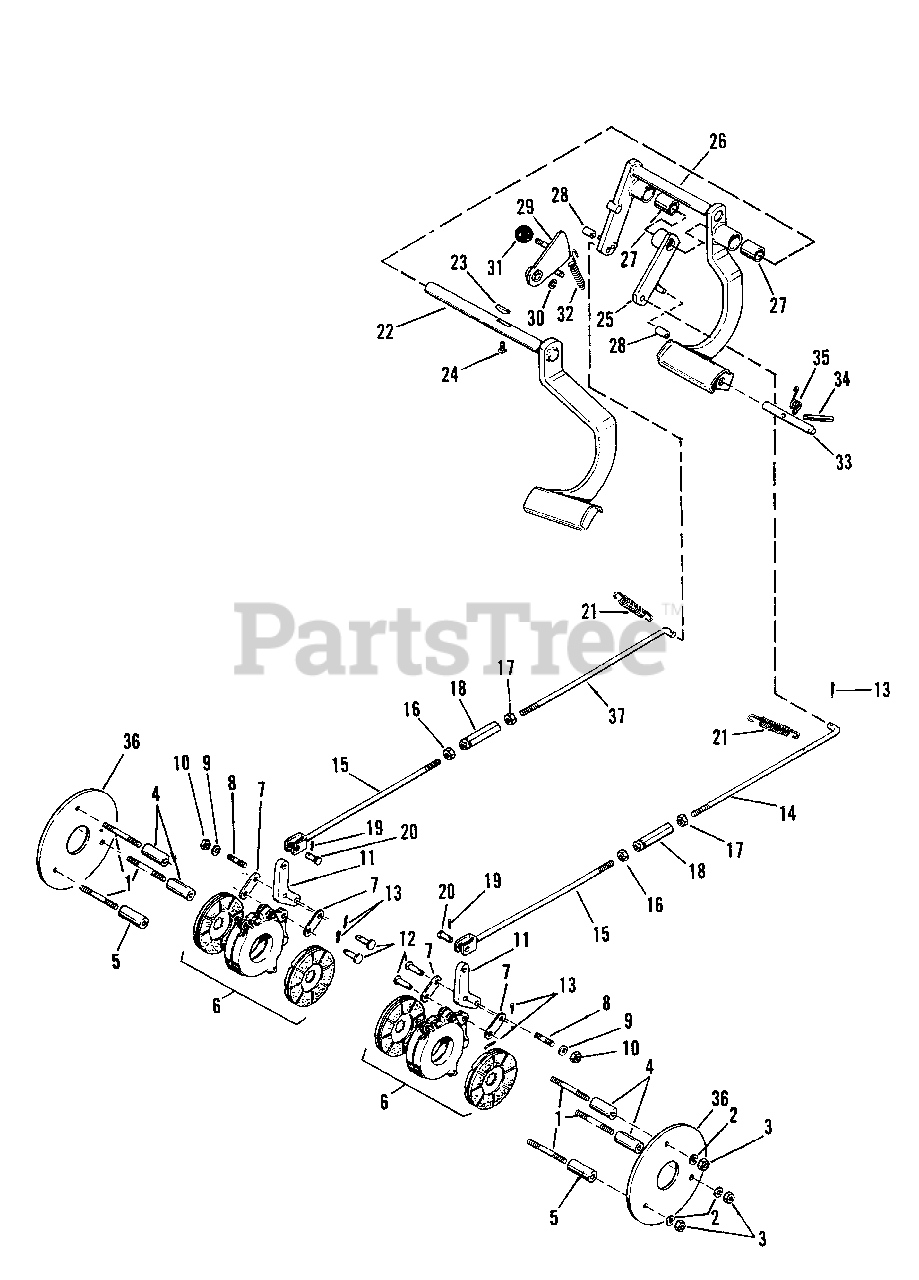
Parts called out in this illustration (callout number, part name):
2	Lock Washer, 3/8"
3	Hex Nut, 3/8"-16
6	Brake Assembly
7	Link Plate
9	Plain Washer, 5/16"
10	Hex Nut, Full Lock, 3/8"-16
11	Brake Lever
13	Cotter Pin, 3/32" x 3/4" lg.
14	Brake Rod, Front
15	Brake Rod Assembly, Rear
16	Hex Nut, Jam, 3/8"-24-R.H.
17	Hex Nut, Jam, 3/8"-24-L.H.
18	Turnbuckle
19	Cotter Pin
21	Spring
22	Brake Lever Assembly, R.H.
24	Set Screw, 5/16"-18 x 3/8" lg.
25	Brake Rod Anchor Assembly
26	Brake Lever Assembly, L.H.
27	Bearing Sleeve
29	Cam Assembly
30	Retaining Ring
33	Pedal Lock Rod
34	Roll Pin
36	Shim Plate
37	Ft. Brake Rod
